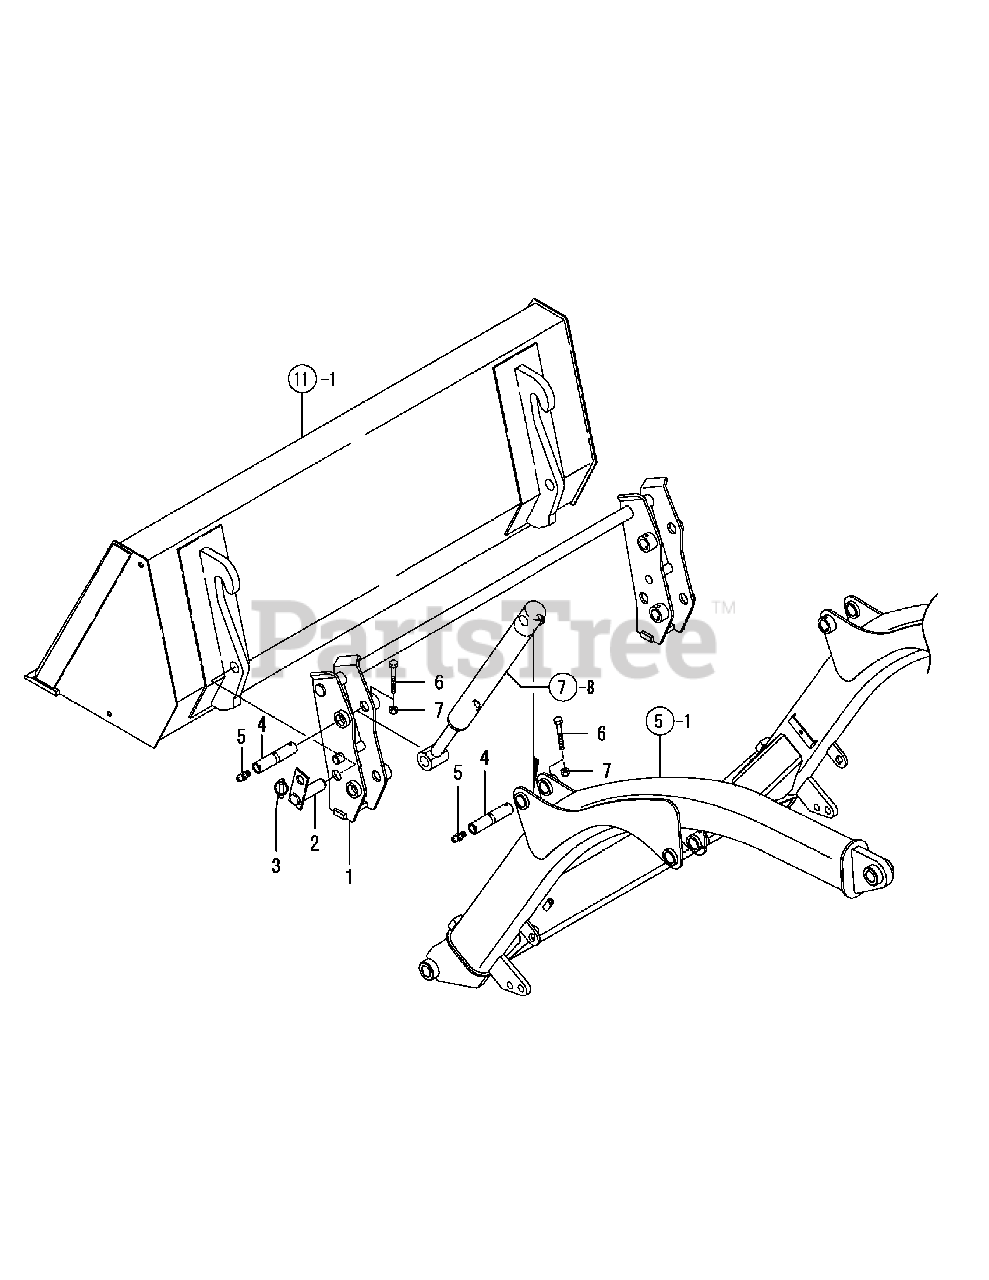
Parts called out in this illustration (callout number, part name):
1	Quick Link Assy
2	Retaining Pin Cmp
3	Pin Assy, Lock
5	Nipple M6F, Grease
6	Bolt M 6X 50 Plated
